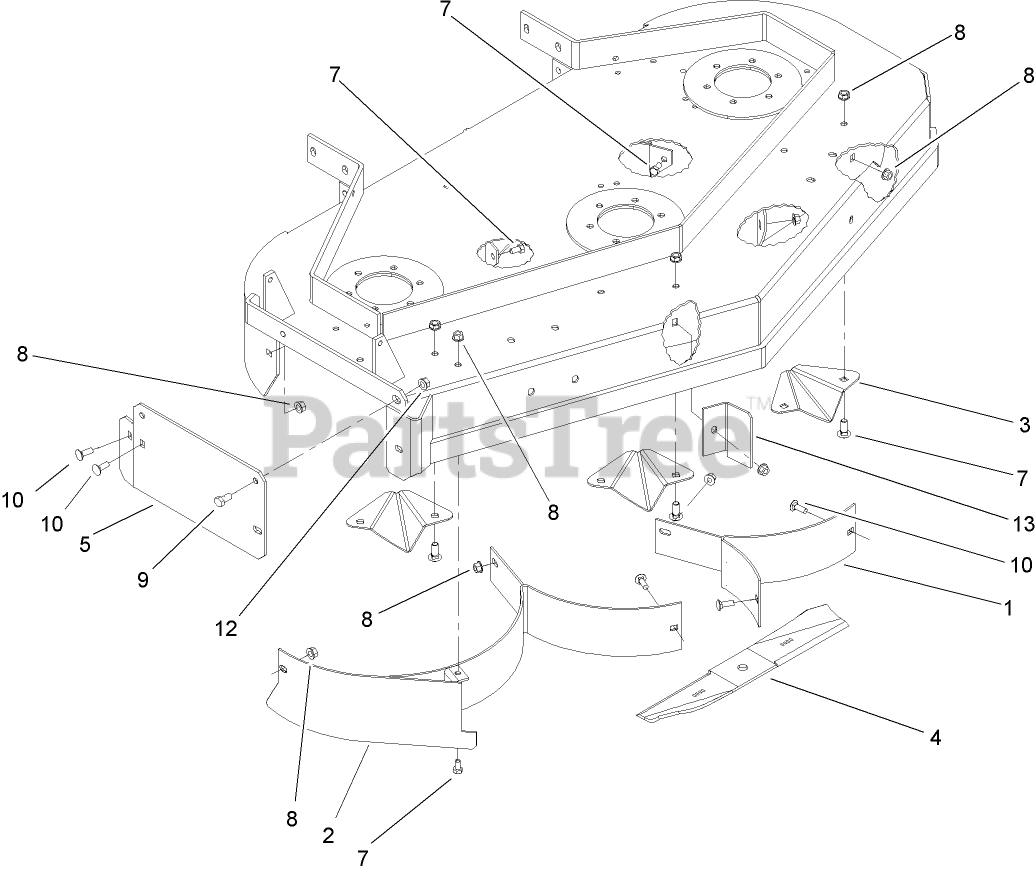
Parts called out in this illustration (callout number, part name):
2	BAFFLE-RH
3	KICKER-DECK
4	BLADE-MULCH
5	PLATE-MULCH
7	SCREW-HH
8	NUT-HF
9	SCREW-HH
10	BOLT-CARR
12	NUT-HHF, WHIZ
13	BAFFLE-BLOCKER
